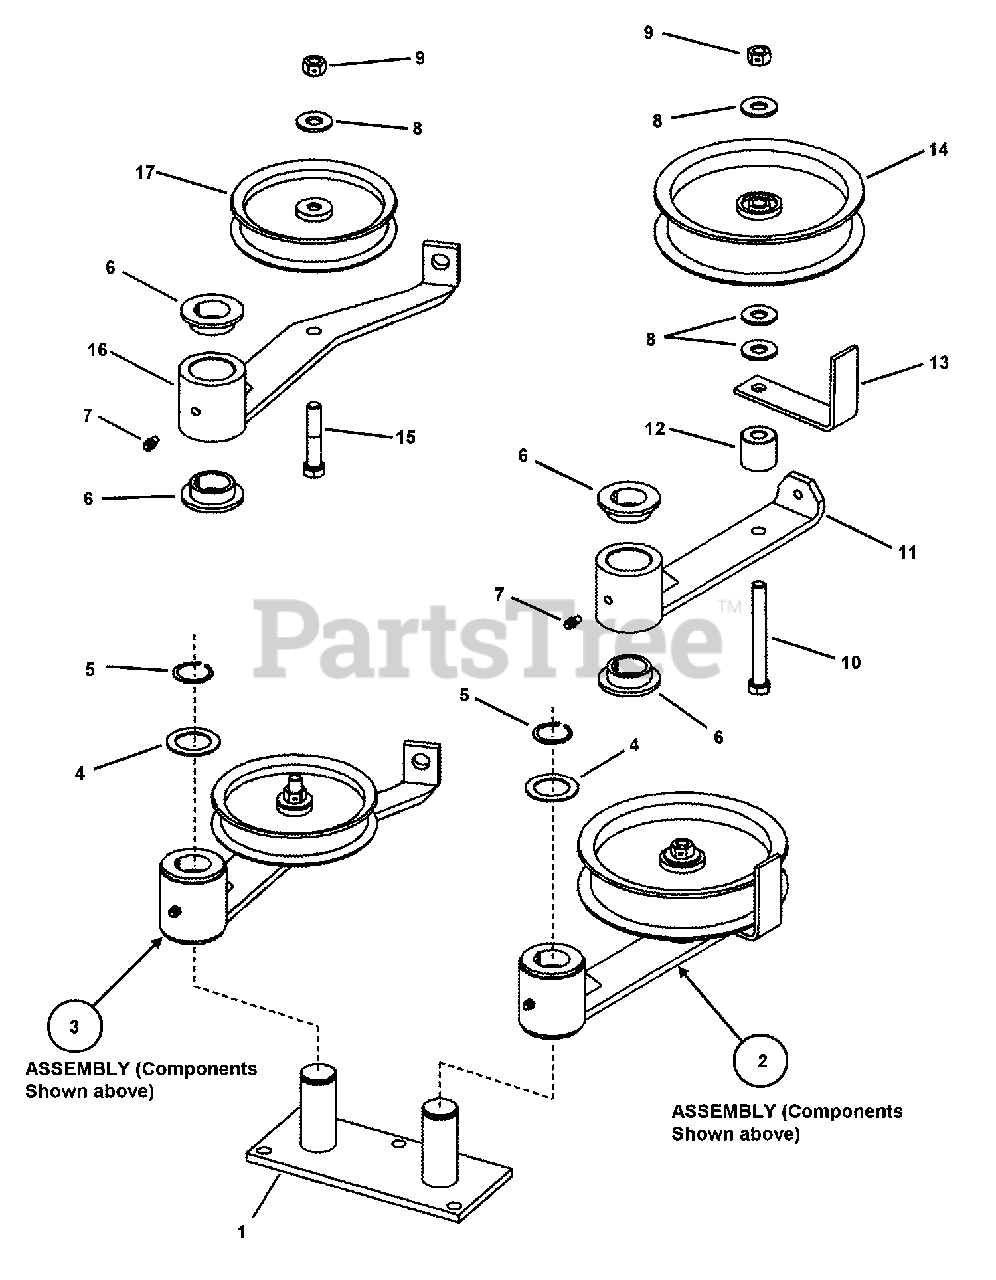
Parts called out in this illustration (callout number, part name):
1	WELDMENT, Idler Plate
2	ASSEMBLY, Primary Idler
3	ASSEMBLY, Secondary Idler
4	BUSHING, 1" Machine
5	RING, 1" External Retaining
6	BUSHING, Idler PM
7	FITTING, 3/16" Straight Lube
8	WASHER, 3/8" USS
9	NUT, 3/8-16 Hex Center Lock, GR 5 or B
10	SCREW, 3/8-16 x 3-1/4" Hex Head Cap, GR 5
11	WELDMENT, Primary Idler Arm
12	BUSHING - Idler
13	RETAINER, Idler Belt
14	PULLEY, Flat Idler
15	SCREW, 3/8-16 x 1-3/4" Hex Head Cap GR 5
16	WELDMENT, Secondary Idler Arm
17	PULLEY, Idler
